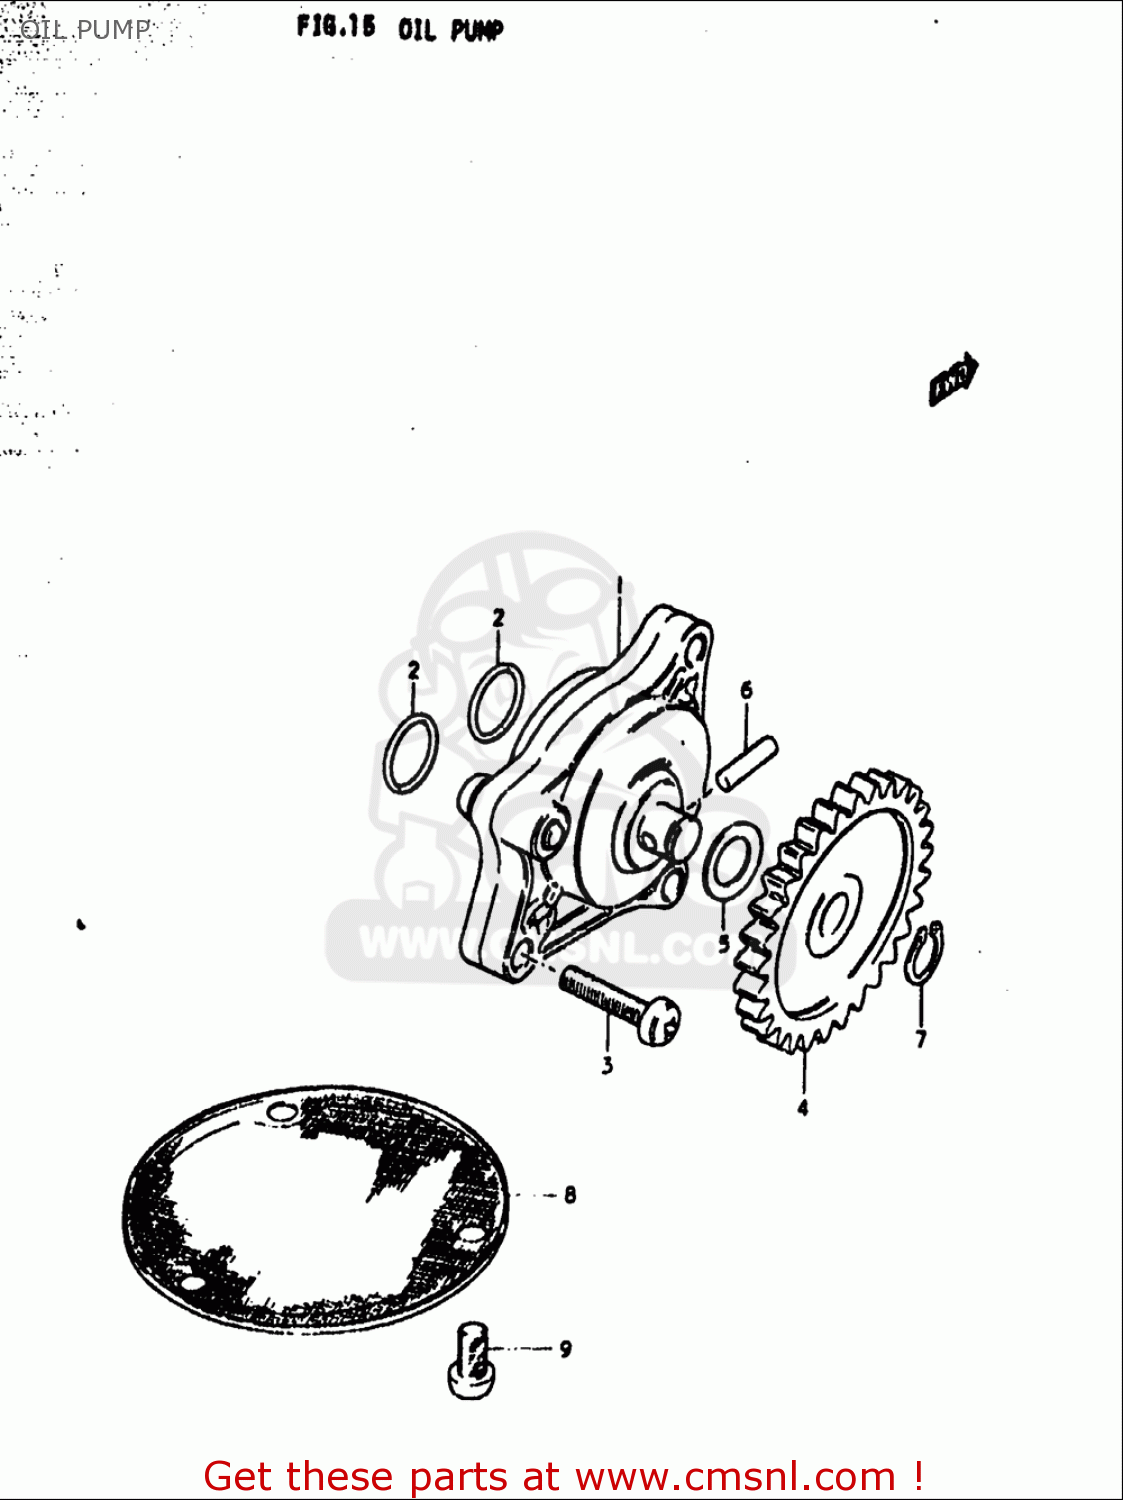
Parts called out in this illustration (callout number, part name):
1	PUMP ASSEMBLY,ENGINE OIL
2	O RING(D:1.9,ID:13)
3	SCREW
4	GEAR,ENG OIL PUMP DRIVEN(NT:33
5	SHIM
6	PIN(4X15.8)
7	CIRCLIP
8	STRAINER,ENGINE OIL
9	SCREW
